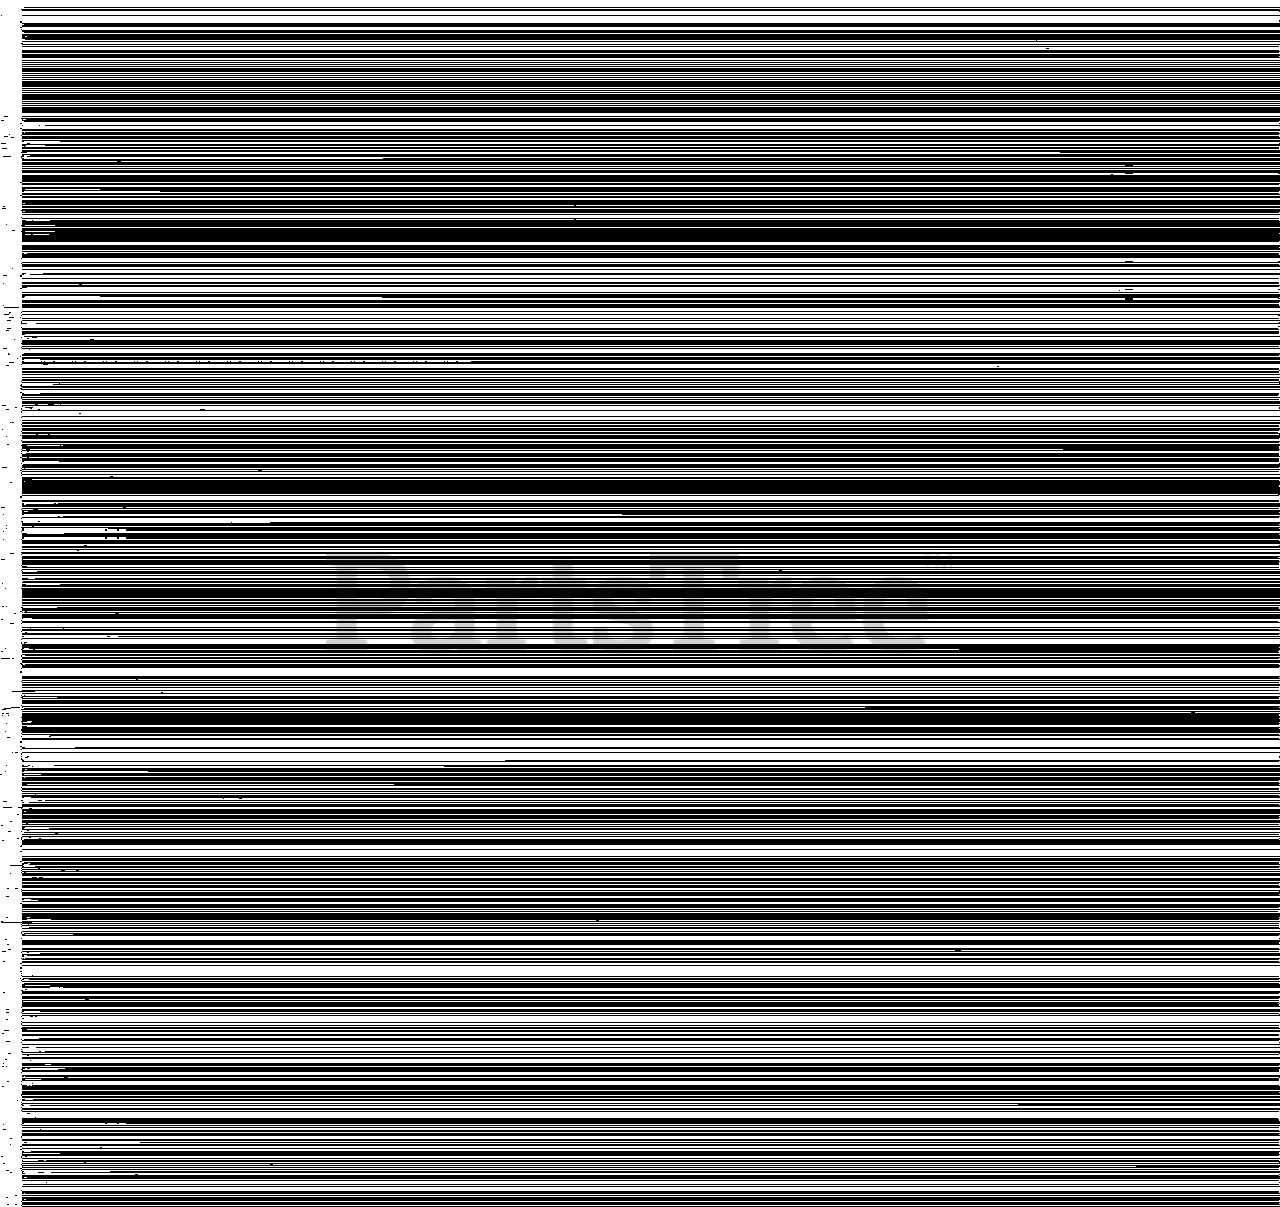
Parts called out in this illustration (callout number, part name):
1	FUEL CAP ASSY
2	FUEL TANK
3	CUSHION
4	FUEL TANK BRACKET
5	BOLT SPW M5×12
7	FUEL TUBE
8	FUEL COCK ASSY
9	FUEL TANK STRAP
